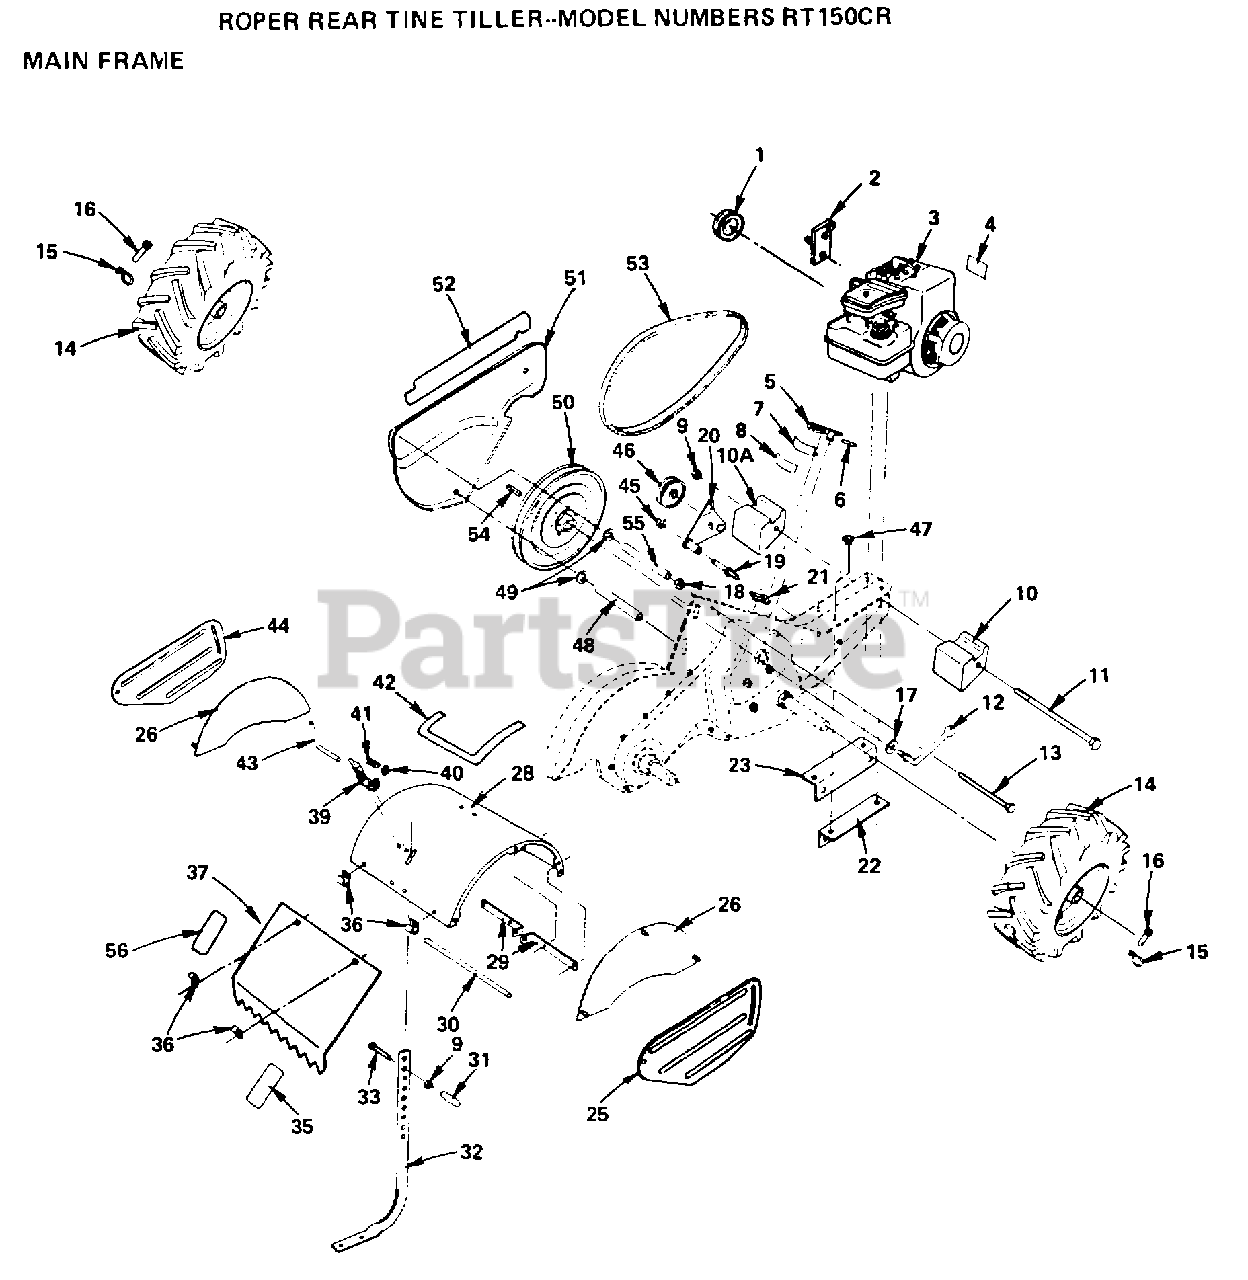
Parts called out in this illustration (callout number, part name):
2	BRACKET ASSY CRT
7	PANEL TI
8	DECAL CRT
9	NUT.HEX.3/8-16UNC
10	COUNTERWEIGHT CRT
10A	COUNTERWEIGHT CRT
11	BOLT CRT
13	BOLT-HEX TI
15	RETAINER M
17	WASHER
18	NUT.HEX.5/16-18
19	SHIFT ARM CRT
21	CONDIUT CLIP T
22	BRACKET RH CRT
23	BRACKET LH CRT
31	GRIP CRT
33	BOLT
36	HINGE CRT
37	SHLD-LEVELING TI
39	LATCH BRACKET TI
40	KLIP RING TI
41	SPRING TI
42	DECAL - TINE SHIELD
43	STAKE PIN TI
45	KLIP RING
46	PULLEY-IDLER TI
49	WASHER
50	"SHEAVE 10"" CRT"
54	KEY T
56	DECAL - DEPTH ADJUSTMENT
